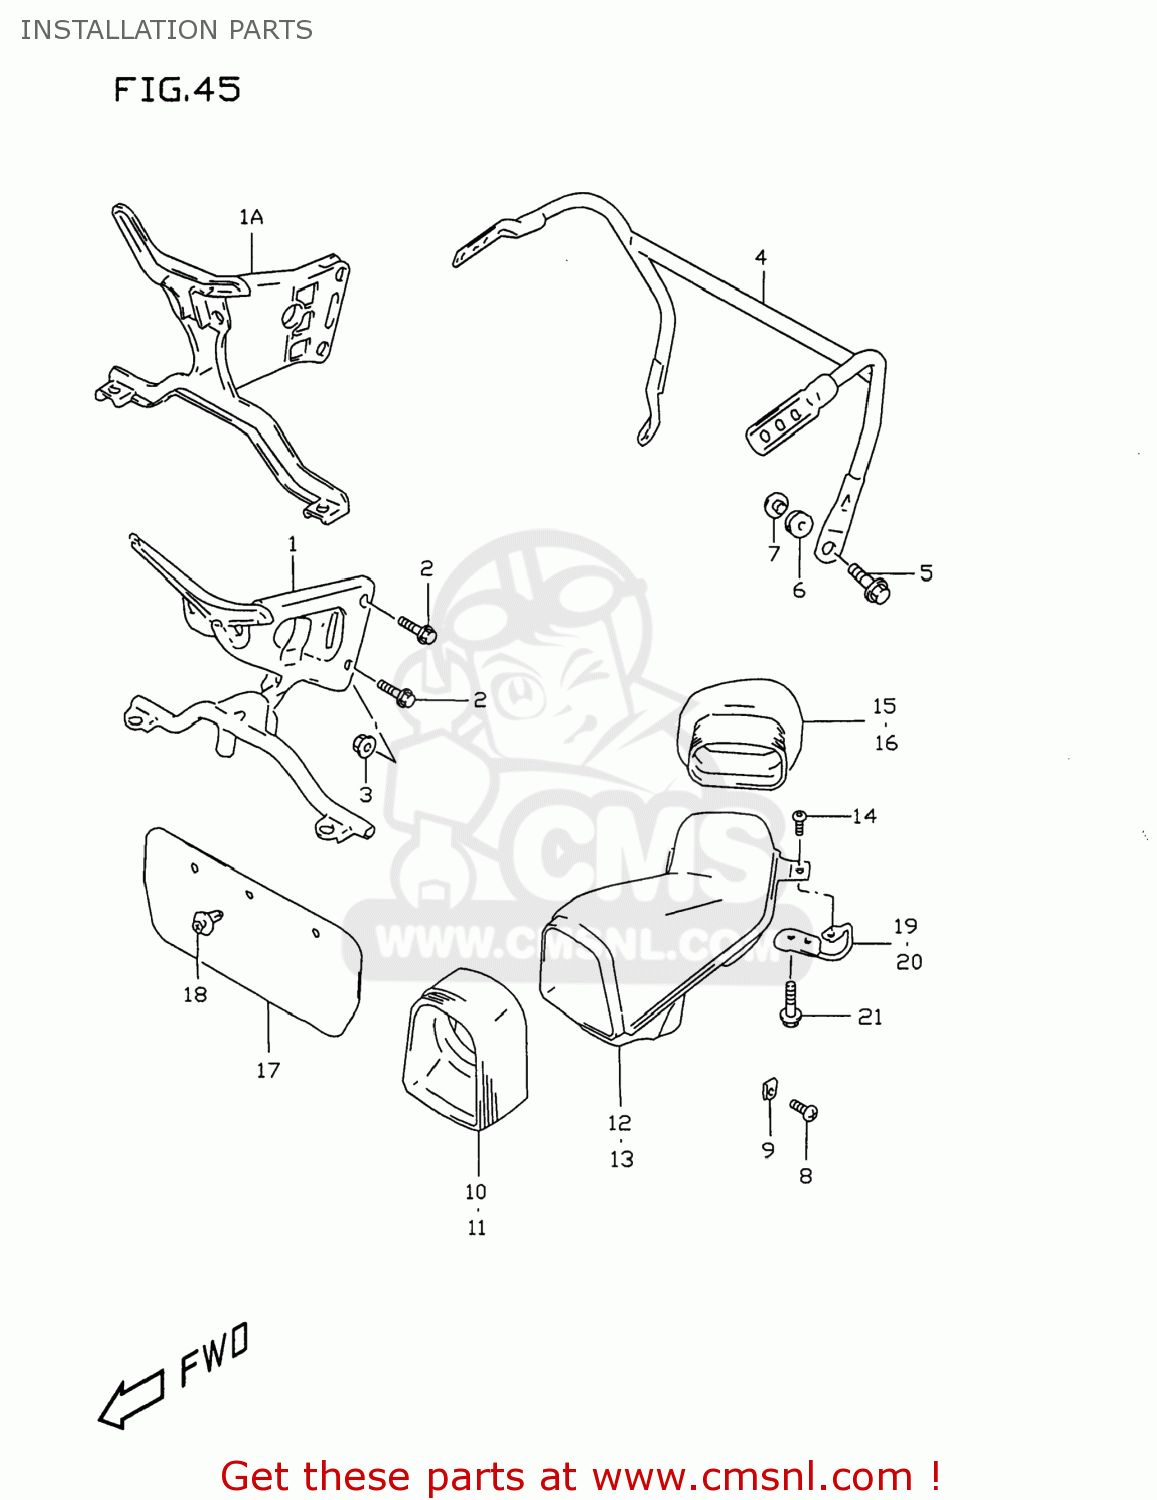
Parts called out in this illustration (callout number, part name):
1	BRACE,COWLING
1A	BRACE,COWLING
2	BOLT
3	NUT
4	BRACE COMP,REAR VIEW MIRROR
5	BOLT(6X25)
6	CUSHION
7	WASHER,MIRROR BRACE,IN
8	SCREW(5X16)
9	NUT,HEADLAMP HOUSING,UPPER
10	JOINT,AIR INTAKE,FR,R
11	JOINT,AIR INTAKE,FR,L
12	PIPE,AIR INTAKE,RIGHT
13	PIPE COMP,AIR INTAKE,LEFT
14	SCREW(5X16)
15	JOINT,AIR INTAKE,RR,R
16	JOINT,AIR INTAKE,RR,L
17	PLATE,AIR GUIDE
18	CLIP
19	BRACE,AIR INTAKE PIPE
20	BRACE,AIR INTAKE PIPE
21	BOLT
